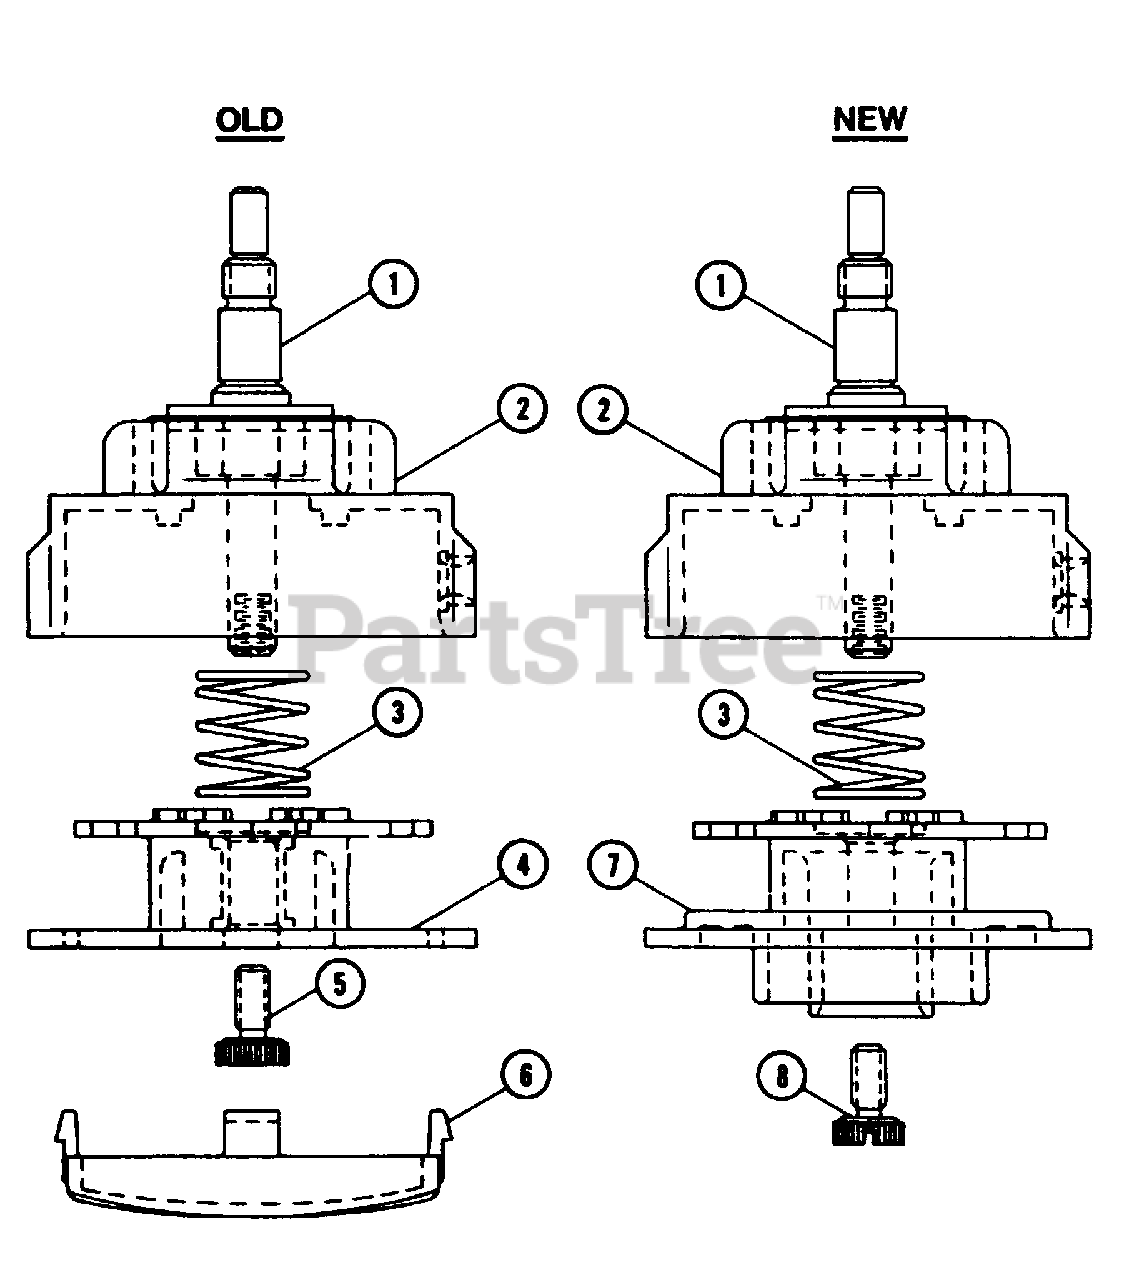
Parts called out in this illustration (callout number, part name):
1	Drive Shaft
2	Spool Housing w/Eyelet
3	Spool Retaining Spring
4	Cartridge Spool
5	Thumb Screw
6	Bump Knob
7	Bump Spool Cartridge with Screw
8	Slotted Thumb Screw
